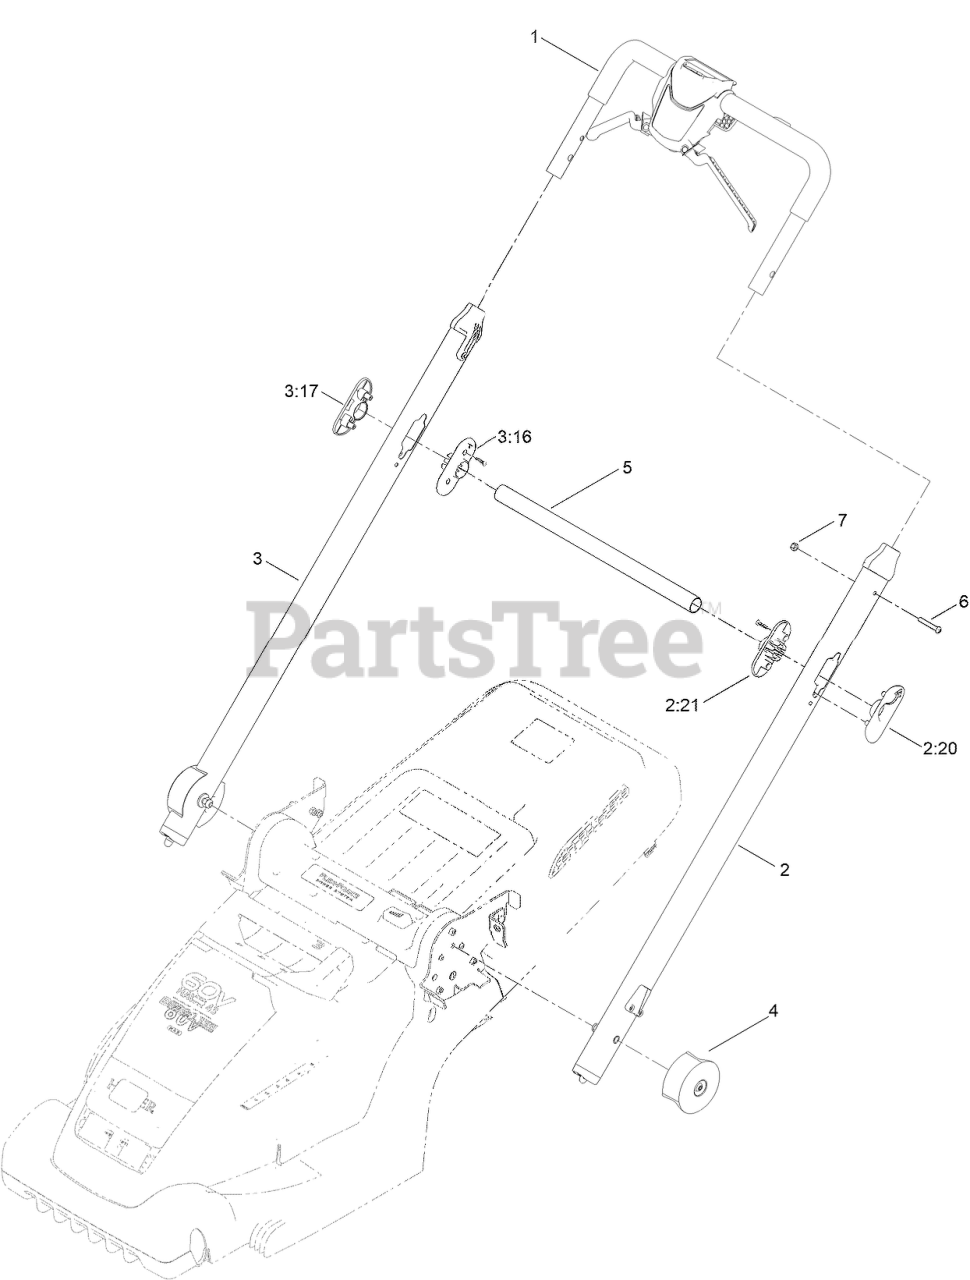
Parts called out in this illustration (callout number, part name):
1	CONTROL LEVER ASM, PROPELLED
2	HANDLEBAR ASM, LH
2:20	HANDLEBAR BRACE - INNER
2:21	HANDLEBAR BRACE, OUTER
3	HANDLEBAR ASM, RH
3:16	HANDLEBAR BRACE - INNER
3:17	HANDLEBAR BRACE, OUTER
4	HANDLEBAR END CAP
5	BRACE, HANDLEBAR RELEASE
6	BOLT, M6X40
7	NUT, M6, NYLOC
